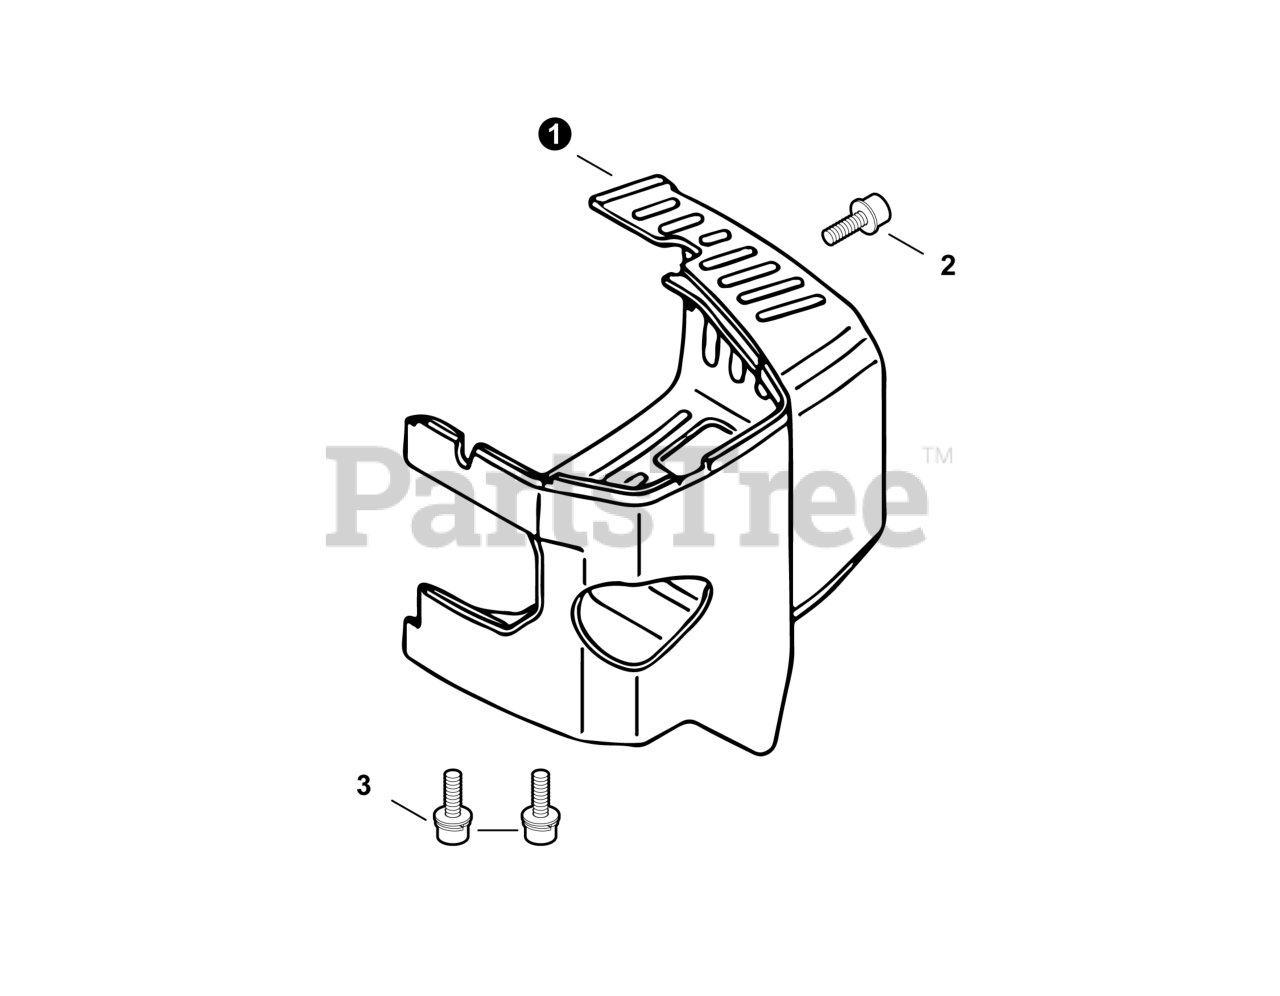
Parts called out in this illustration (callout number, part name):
1	COVER, ENGINE
2	BOLT 4x8
3	SCREW 4x18
